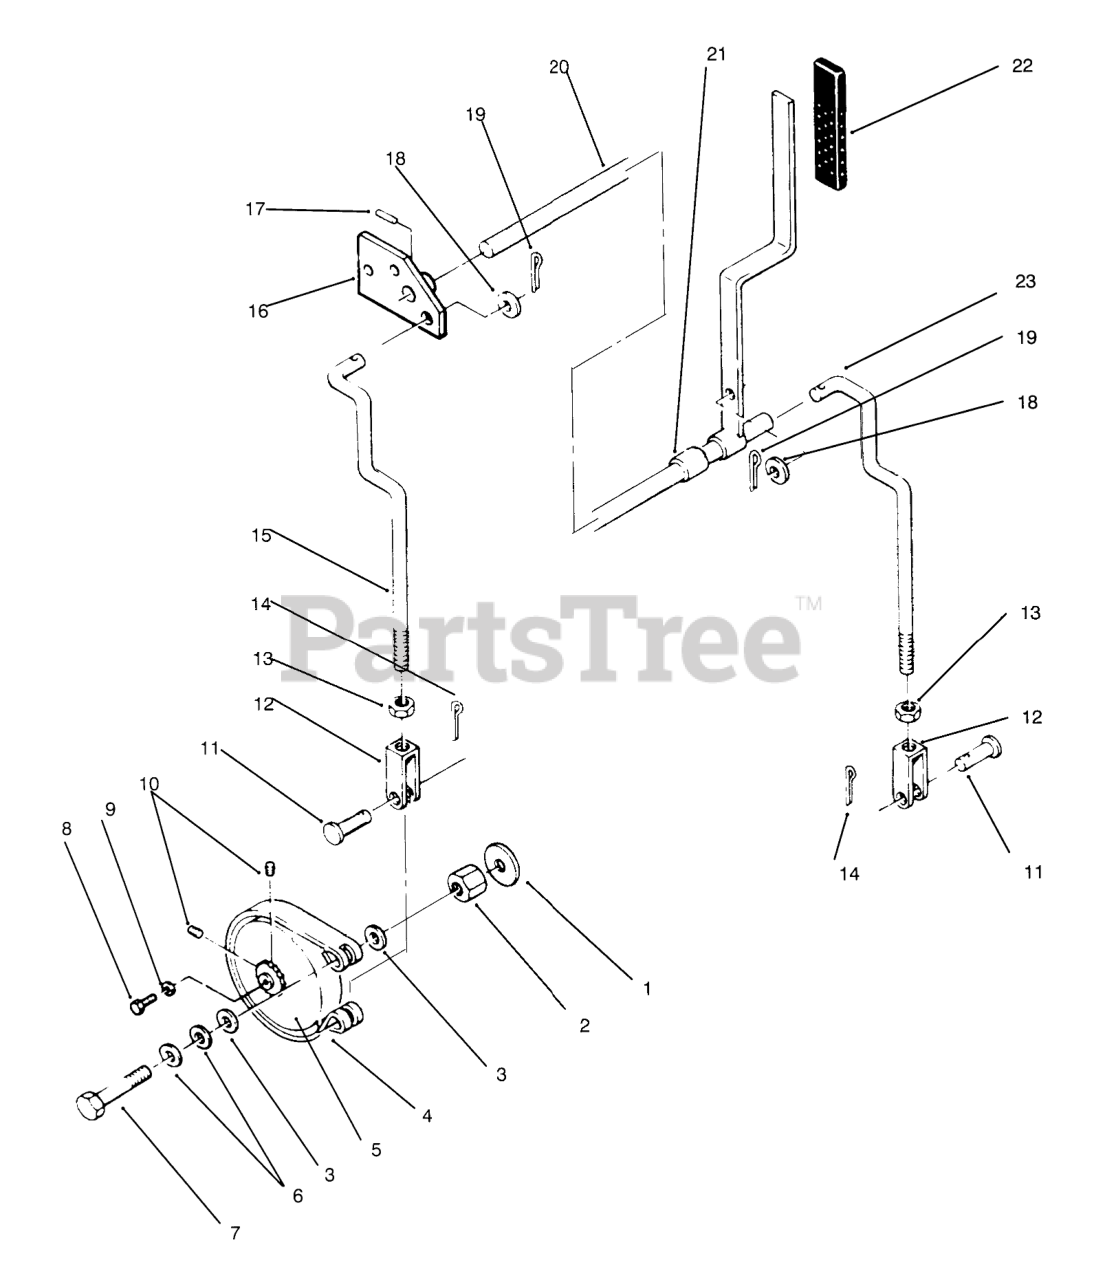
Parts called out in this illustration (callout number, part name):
1	WASHER
2	NUT-COUPLING
3	WASHER-FLAT
4	BRAKE-BAND
5	ASS'Y-DRUM SPROCKET
6	WASHER-SPRING
7	SCREW-HH
8	SCREW-HH
9	WASHER
10	SCREW-SET
11	PIN-CLEVIS
12	ASSY-YOKE BRAKE
13	NUT-HEX
14	PIN-COTTER
15	ROD-BRAKE R.H.
16	ASSY-PARKING BRK B
17	SPIROL PIN H D
18	WASHER-PLAIN
19	PIN-COTTER
20	ASSY-PARKING BRK
21	SPACER-PARKING BR B
22	GRIP-HANDLE
23	ROD-BRAKE L.H.
